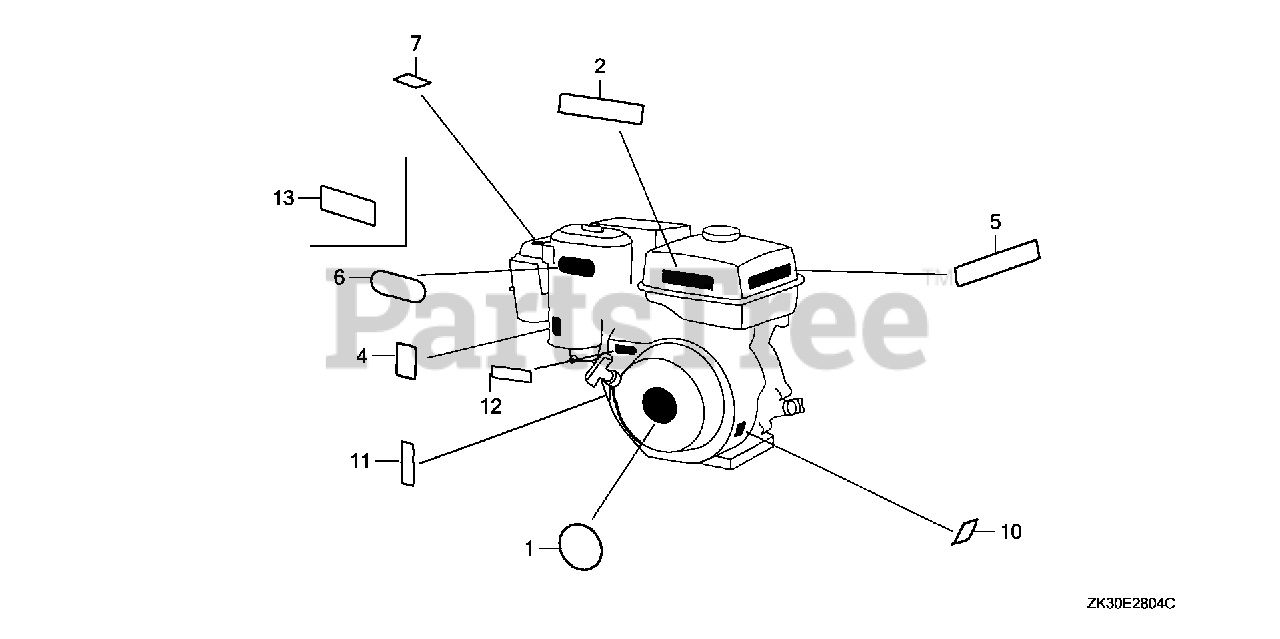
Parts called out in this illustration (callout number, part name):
1	EMBLEM (11. (HONDA)
1	EMBLEM (GX340)
2	LABEL, CAUTION (ENGLISH, ETC.)
4	MARK, CHOKE (ORANGE)
5	MARK, OIL ALERT (GERMAN)
5	MARK, OIL ALERT (FRENCH)
5	MARK, OIL ALERT (ENGLISH)
